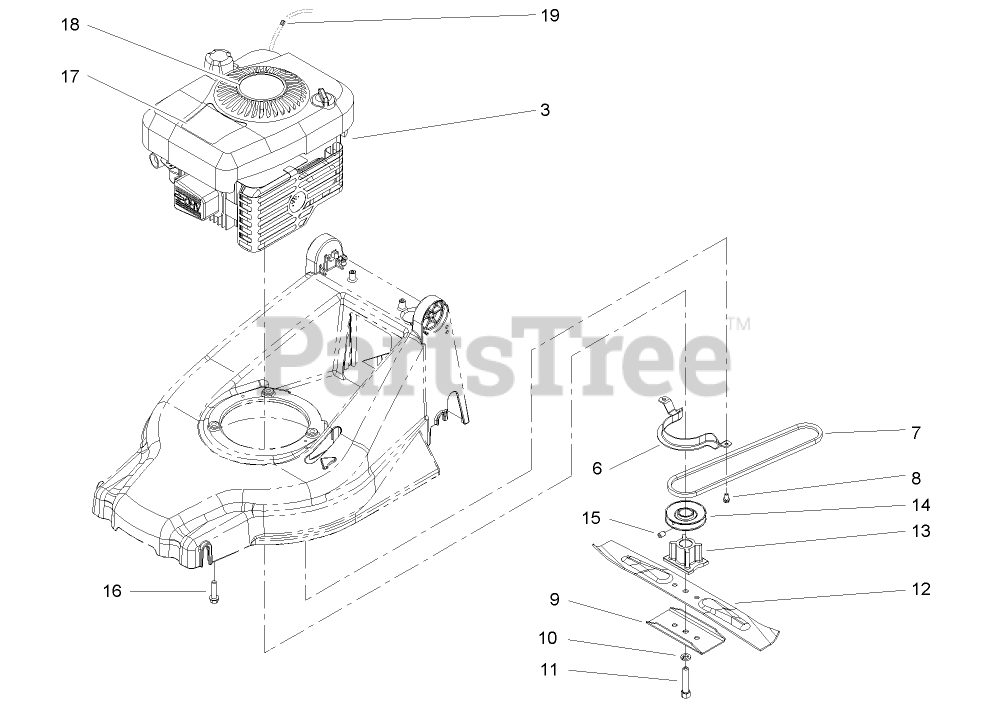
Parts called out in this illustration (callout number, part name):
3	Loose Parts Package
6	GUIDE-BELT, ENGINE
7	V-BELT
8	SCREW-HWH
9	STIFFENER-BLADE
10	WASHER-LOCK
11	BOLT-BLADE
13	RETAINER-BLADE
14	PULLEY ASM
16	SCREW-HWH
17	DECAL-RECOIL
18	DECAL-RECOIL, RECYCLER
19	STOP-ROPE
